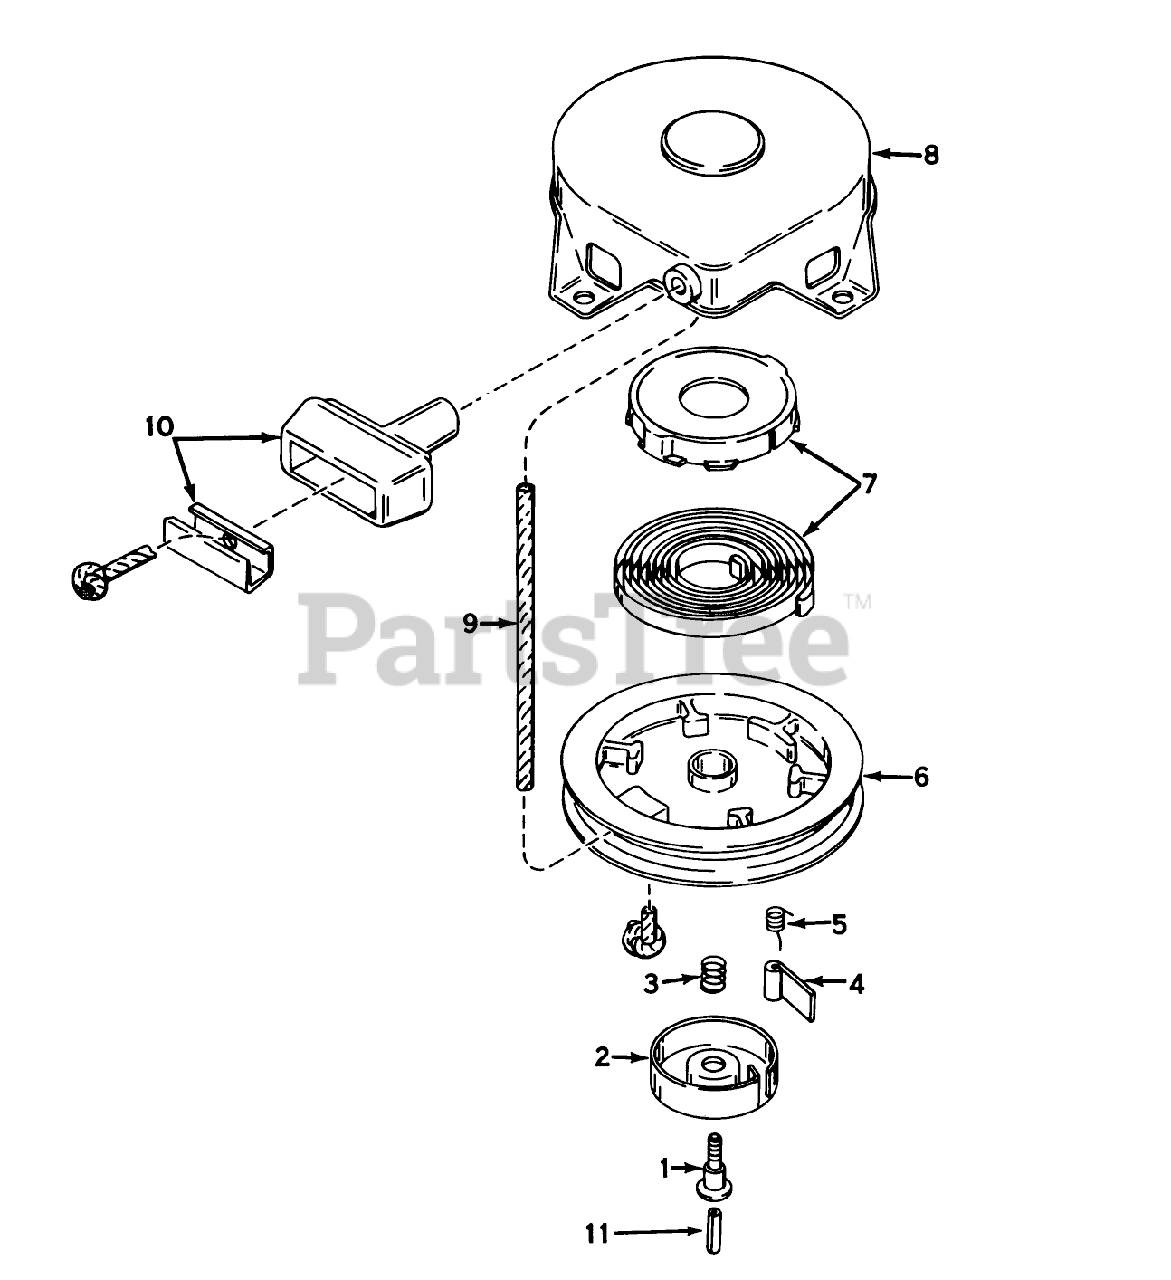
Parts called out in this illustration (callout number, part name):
1	Screw
2	Retainer
3	Spring-Brake
4	Dog-Starter
5	Spring-Dog
6	Pulley
7	Spring Keeper Assy
8	STARTER HOUSING ASSY
9	Rope Starter
10	Assy., Starter
11	Centering
